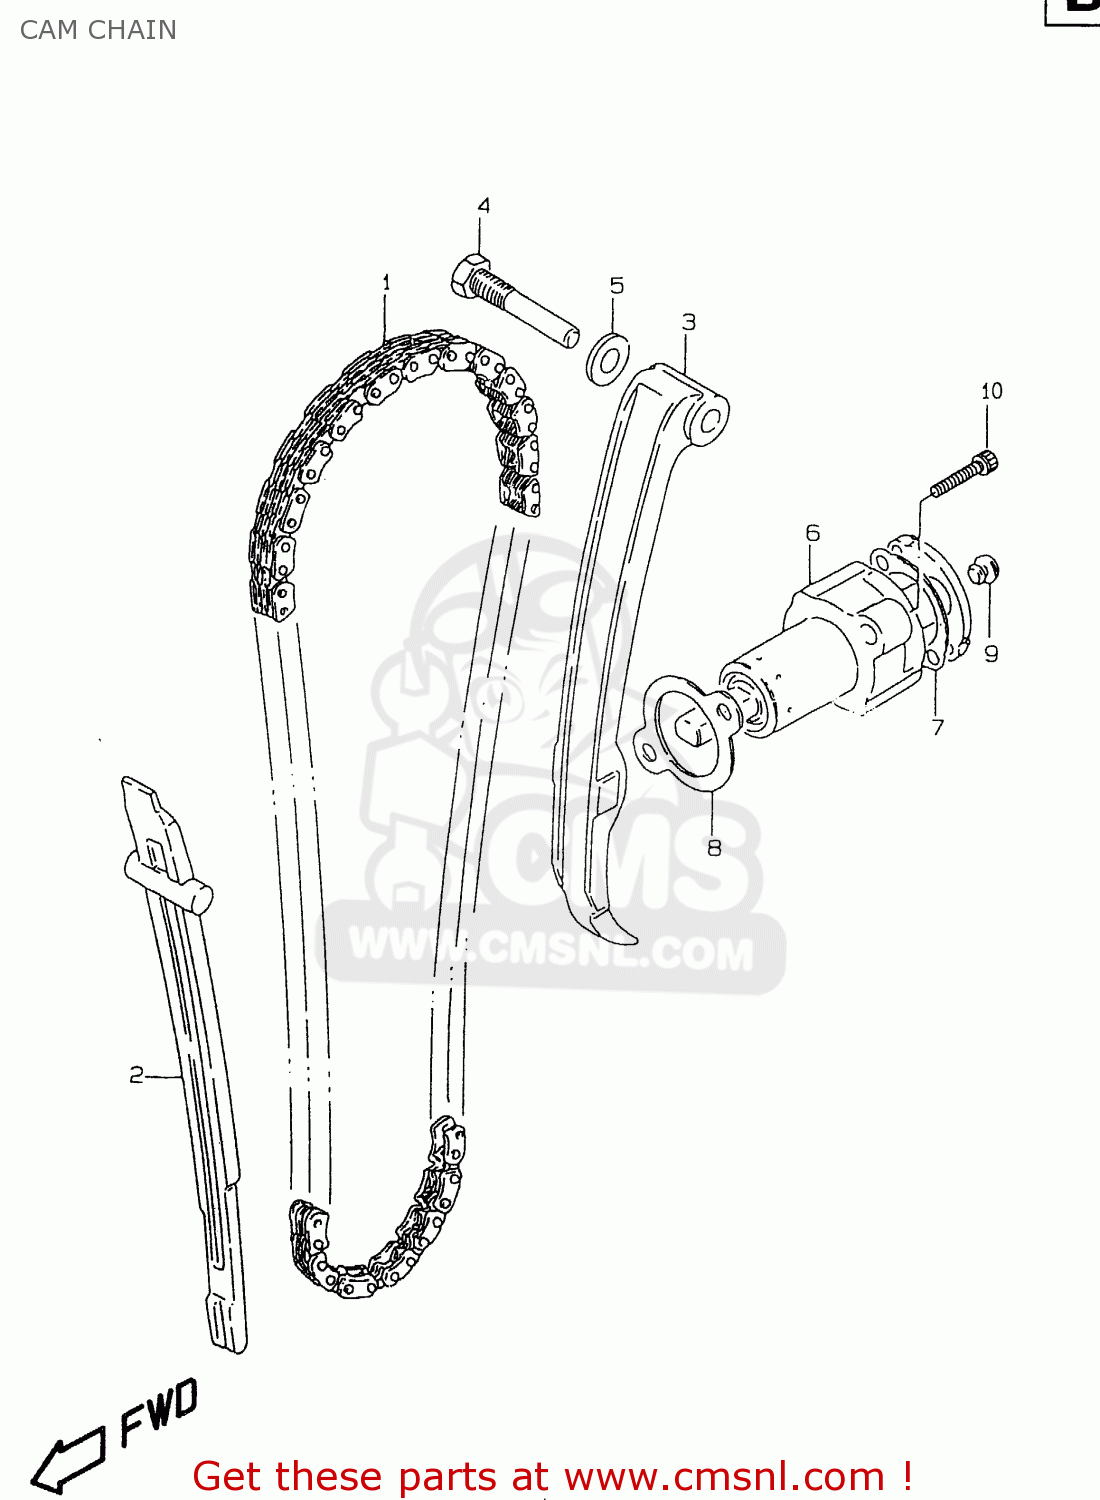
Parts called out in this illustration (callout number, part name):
1	CHAIN,CAMSHAFT DRIVE
2	GUIDE,CAM CHAIN
3	TENSIONER,CAM CHAIN
4	BOLT,CAM CHAIN TENSIONER
5	GASKET 8.2X14X1 (NAS)
6	ADJUSTER ASSY,TENSIONER
7	GASKET,ADJUSTER CAP (NAS)
8	GASKET,TENSIONER ADJUSTER (NAS)
9	PLUG,ADJUSTER
10	BOLT
